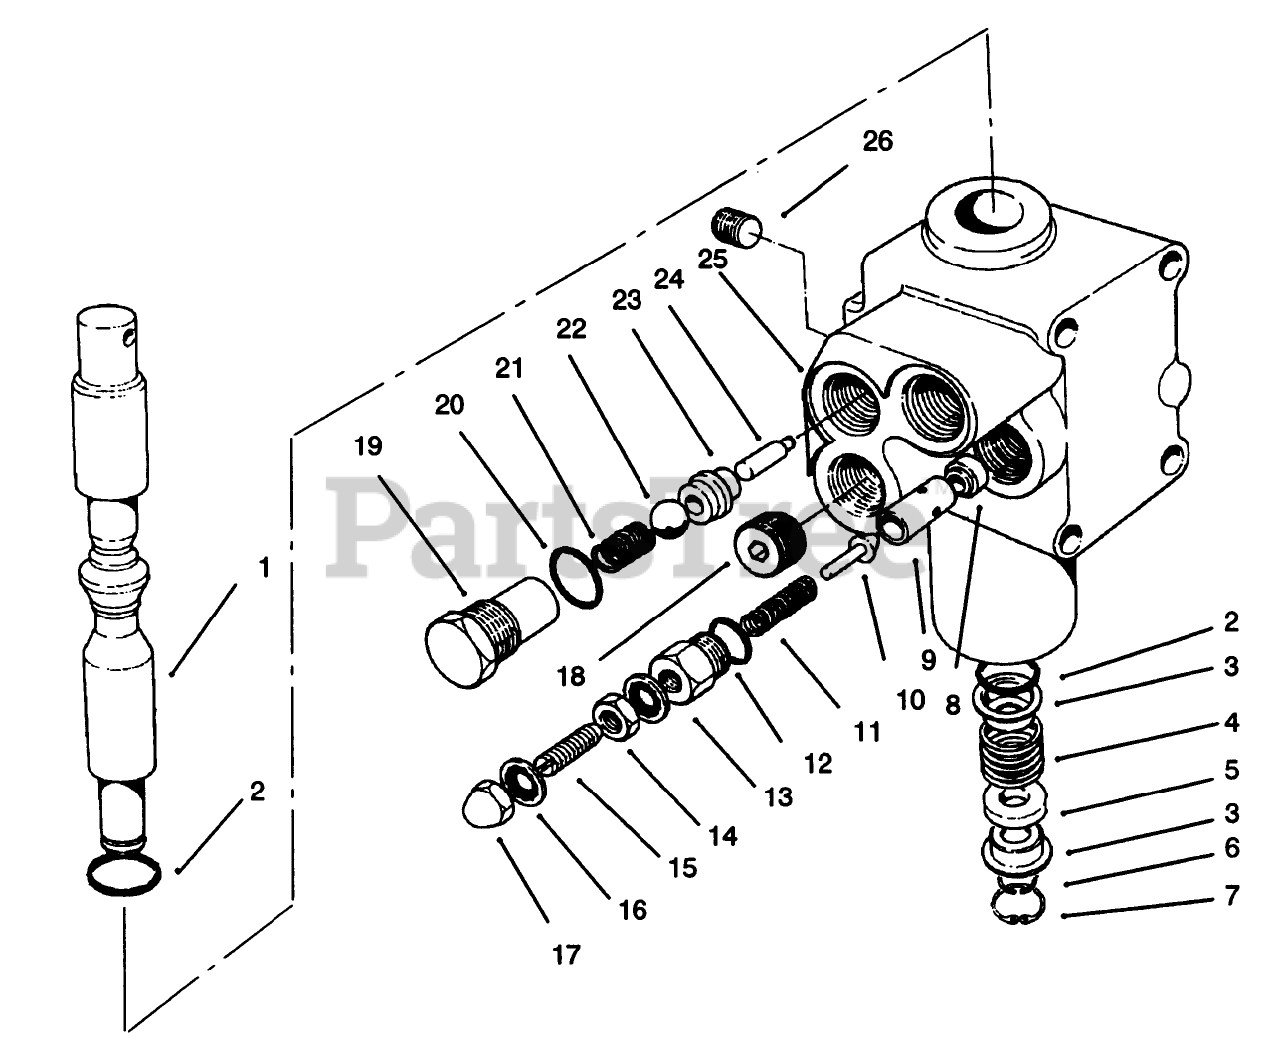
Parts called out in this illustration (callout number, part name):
1	SPOOL
2	O-RING
3	RETAINER
4	SPRING
5	FLOAT SPACER
6	RING-SNAP
7	RING-SNAP
8	SEAT-RELIEF
9	Guide
10	Plunger
12	"O"Ring
13	Cap-PV Adjustment
14	Nut
15	Screw Set
16	Stat O Seal
17	Nut-Acorn
20	O-RING
21	SPRING
23	SEAT-VALVE
